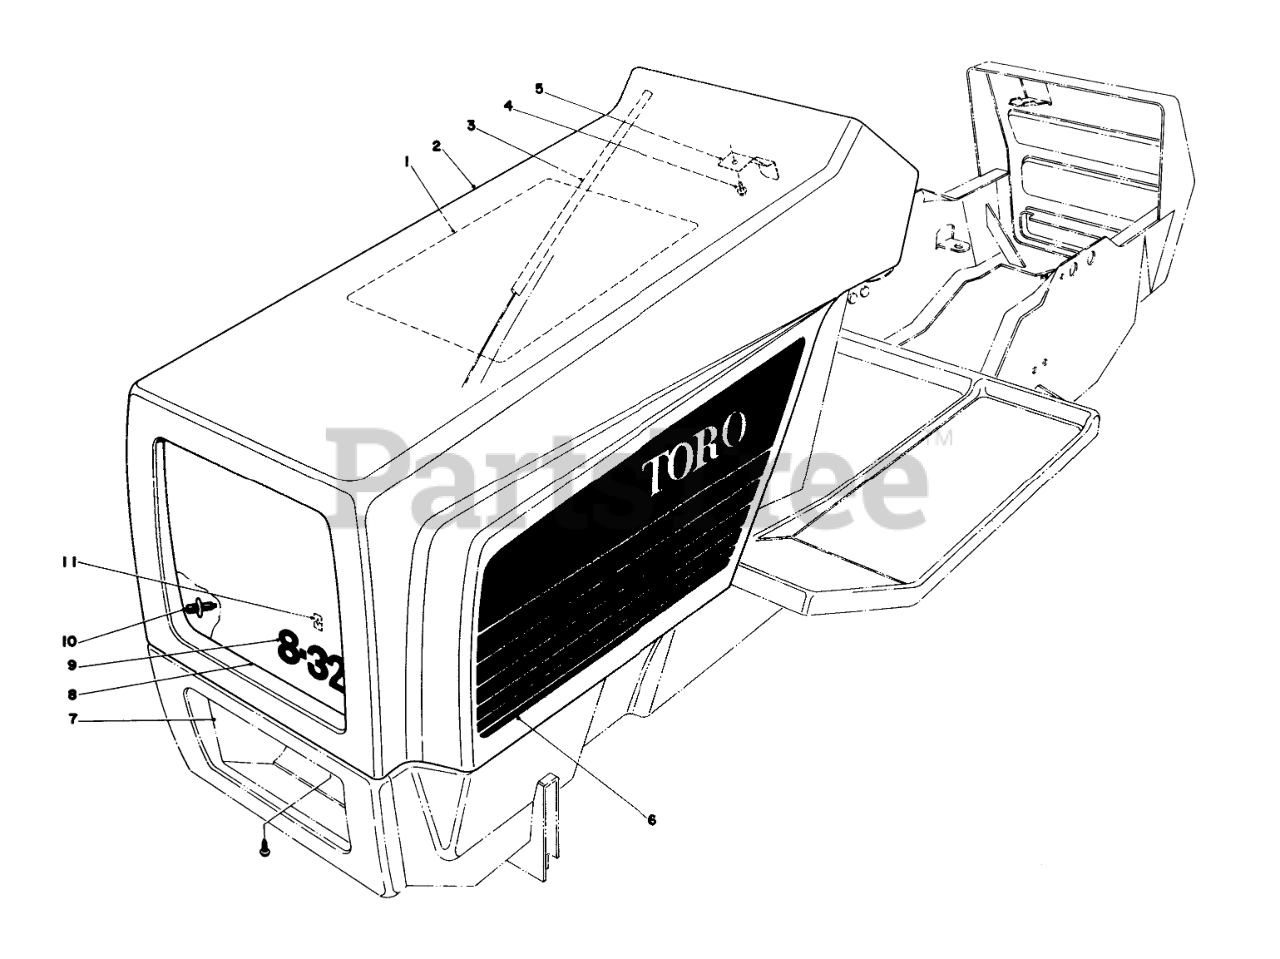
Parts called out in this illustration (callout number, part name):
1	Decal Service
3	RUBBER EXT SEAL
4	Screw
5	SPRING LATCH
6	Decal Hood LH.
7	LOWER GRILLE
8	HOOD GRILLE
9	Nameplate Grille
10	HINGE BRKT STUD
